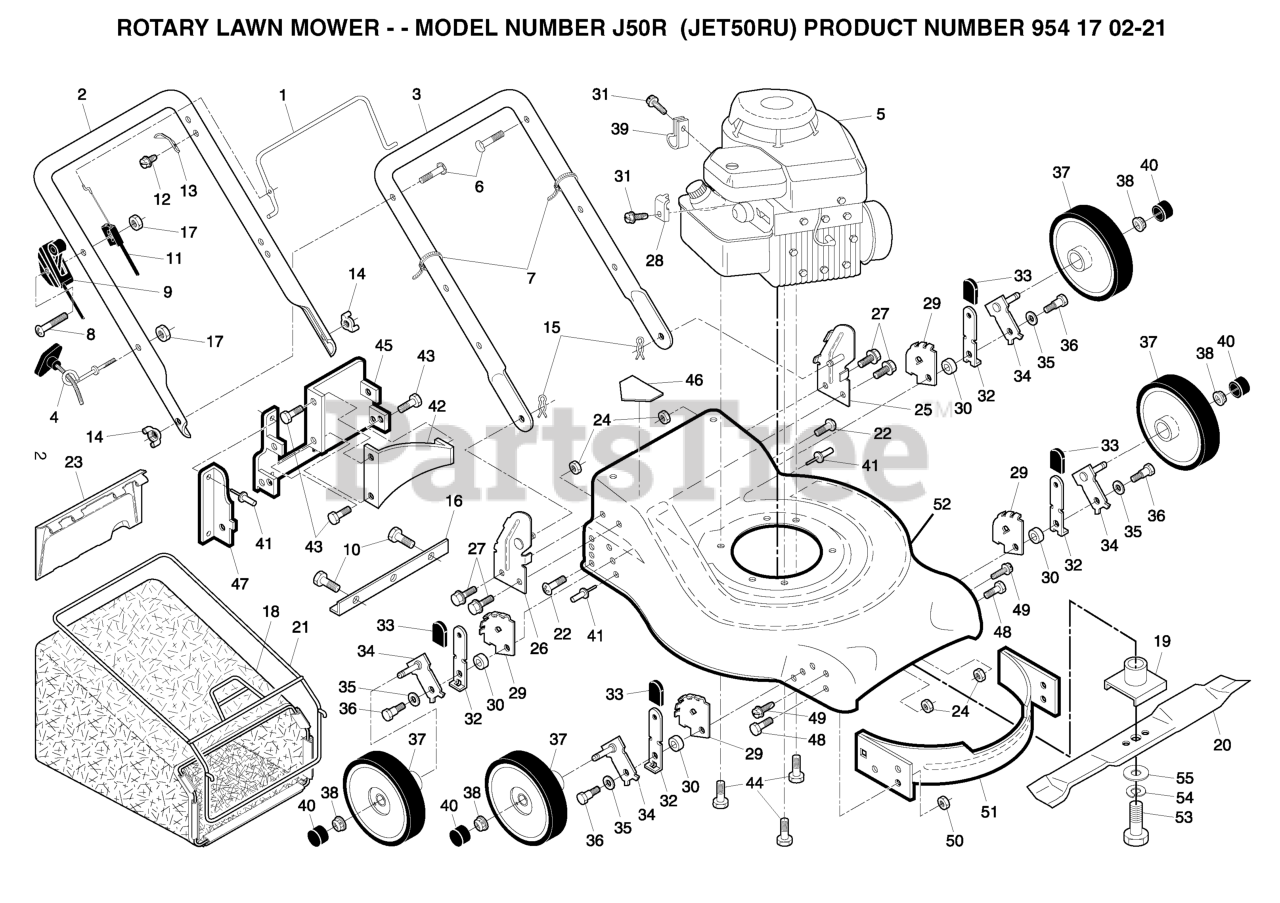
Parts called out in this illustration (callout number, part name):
1	CONTROL BAR
2	UPPER HANDLE
3	HANDLE
4	ROPE, GUIDE
6	HANDLE BOLT
7	TIE GUIDE
8	SCREW.PAN.HEAD
11	CABLE.MZR.51.RT.SP./PU.
13	BRACKET UPSTOP
14	NUT WING PM
15	HAIRPIN COTTER
16	REPL BY 532 14 61-43
17	NUT
19	BLADE ADAPTOR
20	BLADE.20.MULCH.(50DK,6020MD)
21	CATCHER.FRAME.WALK
22	HINGE SCREW
23	REAR DOOR ASSEMBLY KIT
24	LOCKNUT PM
25	HANDLE BRACKET ASSEMBLY - LEFT
26	HANDLE BRACKET ASSEMBLY-RIGHT
27	SELF-TAPPING SCREW 5/16-18X3/4
28	CABLE CLAMP(ENGINE)
29	WHEEL ADJUST BRACKET
30	RP SPACER HT ADJ
31	SCREW.HEX.HEAD.WASHER.10-16
32	SELECTOR SPRING
34	AXLE, REAR
35	WASHER.BELLEVILLE (3 2 LB)
36	BOLT
37	WHEEL
38	HEX FLANGE LOCKNT
39	GUIDE CLIP PM
41	RIVET BLIND
44	BOLT 3/8-16X1-1/8
46	DECAL.INTERNATIONL.CUTFINGER
47	SIDE BAFFLE
48	SCREW 1/4X20
50	LOCK NUT
53	SCREW, HEX HD 3/8-24 X 1-3/8
54	LOCKWASHER
55	WASHER,HARDEN
